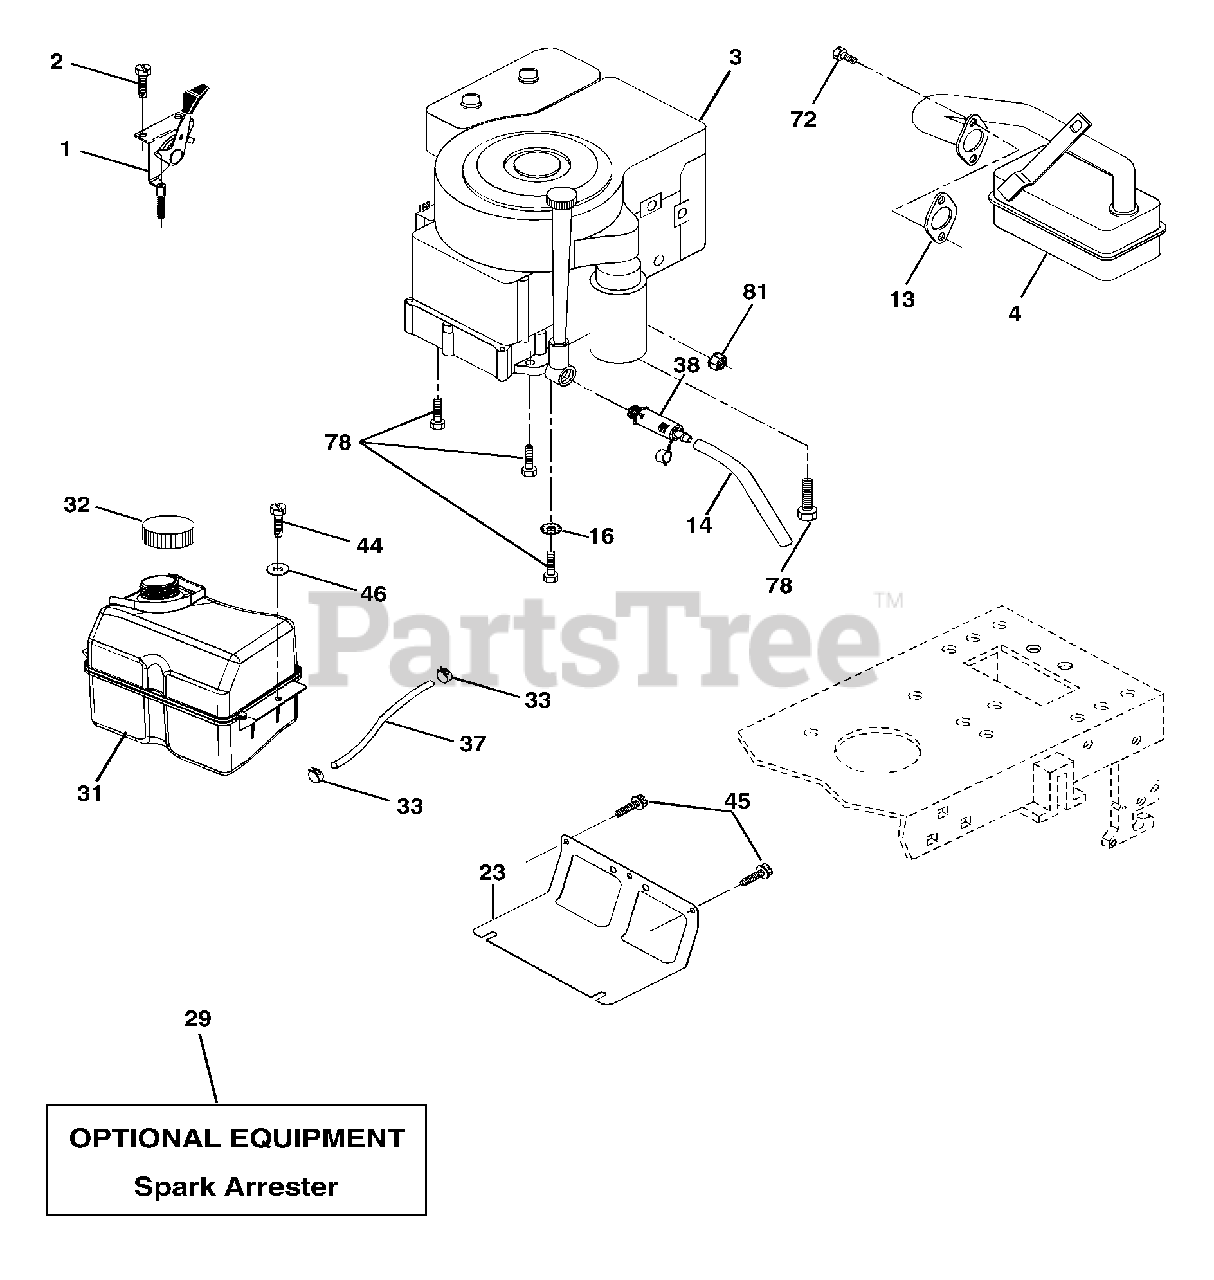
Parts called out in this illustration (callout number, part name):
1	Control Throt /Ch Flag
2	Screw Hex Thd Cut 1/4-20x1/2
4	Muffler Exhaust
13	Gasket
14	Tube Drain Oil Easy
16	Washer Lock Ext Tooth 3/8
23	Shield Browning/Debris Guard
29	Arrestor Spark
31	Tank Fuel
32	Cap Asm Fuel W/sym Vented
33	Clamp Hose Blk
37	Line Fuel 20"
38	Plug Drain Oil Easy
44	Screw Hexwsh Thdrol 1/4-20x3/4
45	Screw Hex Wsh Thdrol 3/8-16
46	Washer 9/32 X 7/8 X 16ga
72	Screw Socket head 5/16-18 x 1
78	Screw 3/8-16 x 1-1/4
81	Nut Keps Hex 1/4-20
